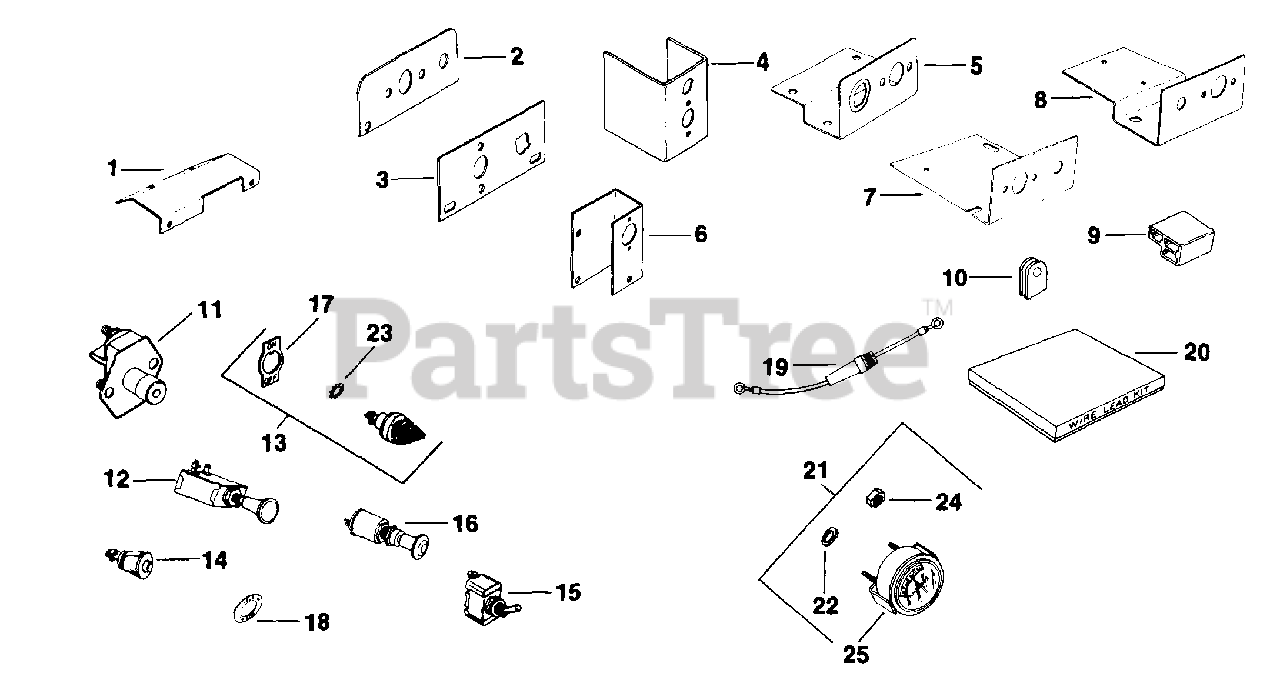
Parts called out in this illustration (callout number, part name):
11	SWITCH - DISCONTINUED
12	SWITCH - DISCONTINUED
17	PLATE - DISCONTINUED
